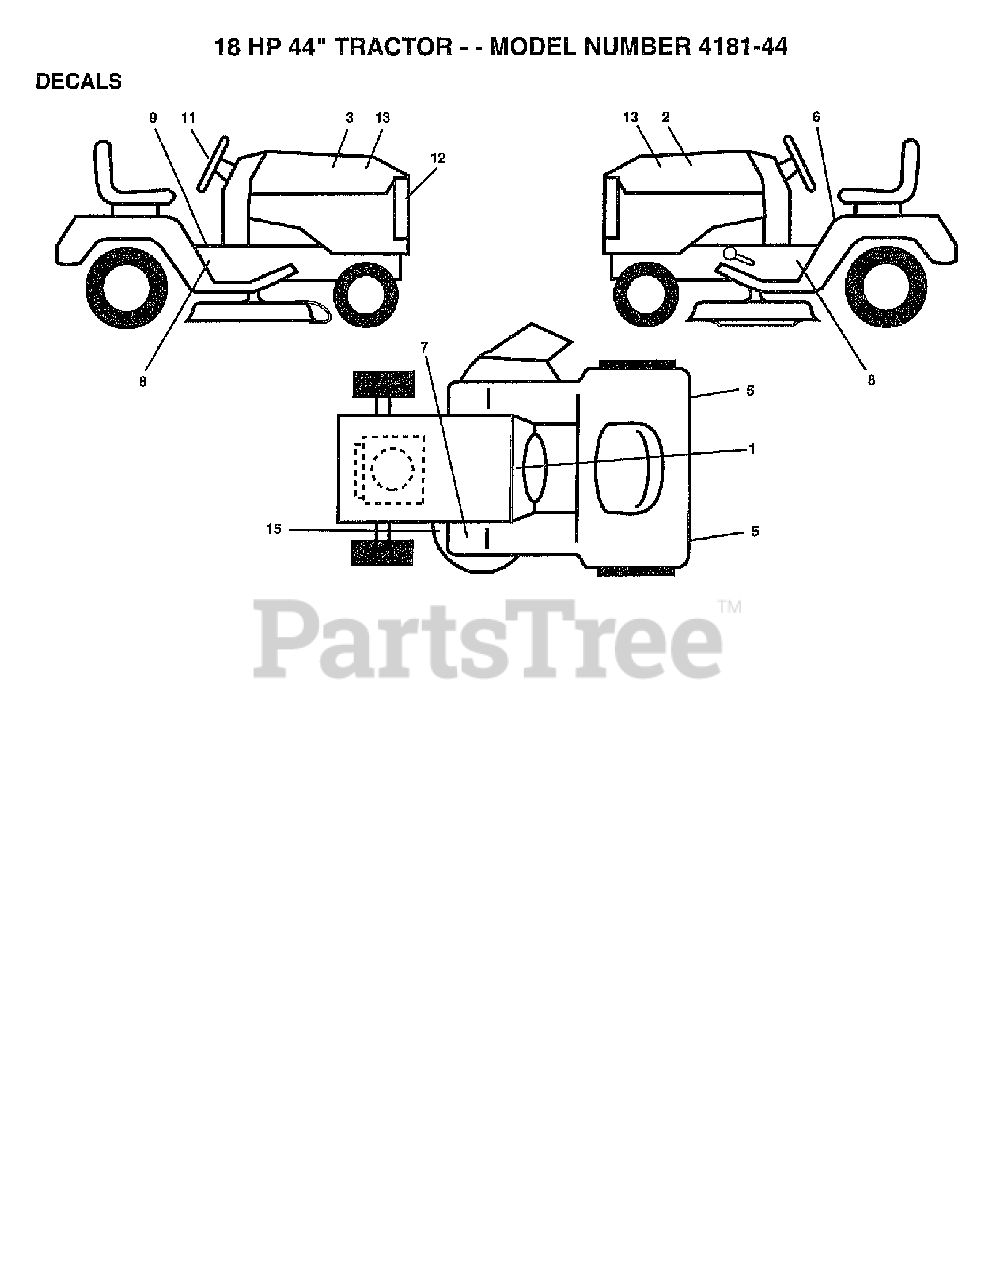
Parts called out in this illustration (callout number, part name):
2	Poulan TBD
3	Poulan TBD
5	REFLECTOR-TAIL YT
6	DECAL LT
8	Poulan TBD
9	DECAL PARK BRAKE
11	Poulan TBD
12	Poulan TBD
13	Poulan TBD
